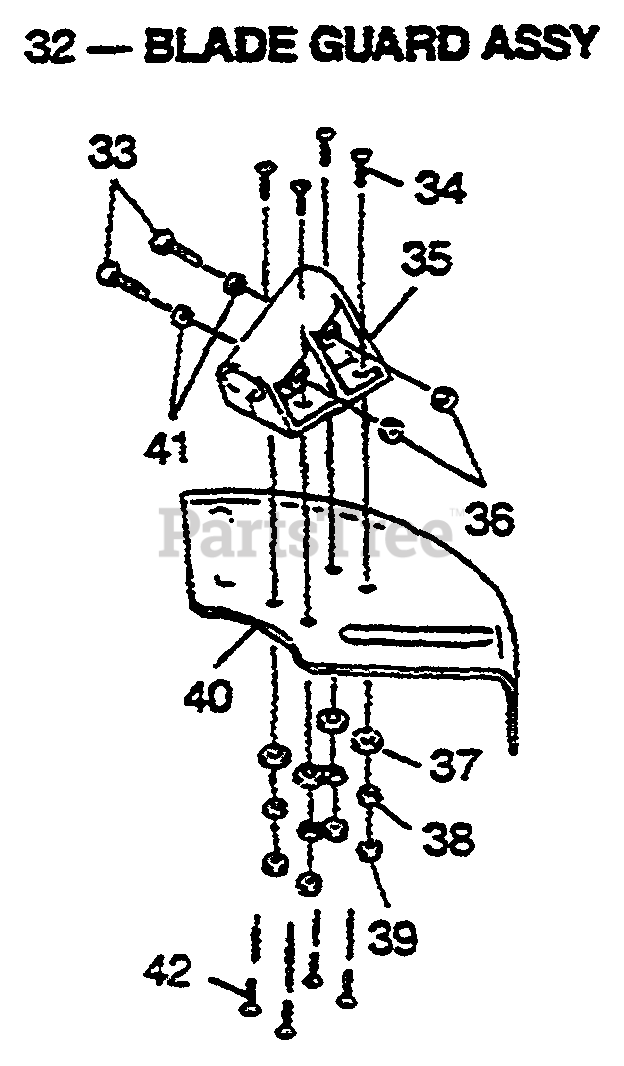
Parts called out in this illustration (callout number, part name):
32	BLADE GUARD ASSY
34	SCREW
35	BRACKET, BLADE GUARD
37	WASHER
38	WASHER
39	NUT
40	GUARD
42	SCREW
